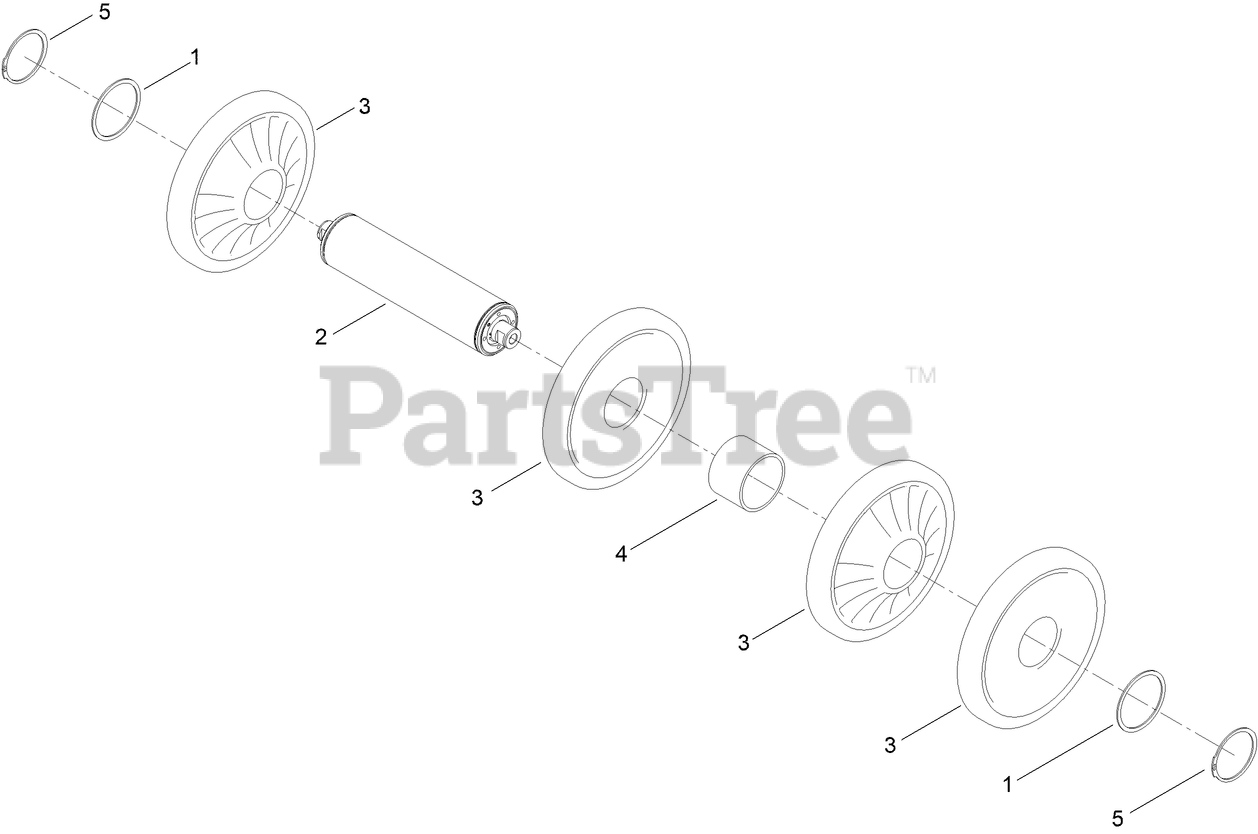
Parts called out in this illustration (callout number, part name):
1	RING-RETAING, TRACK WHEEL
2	AXLE ASS'Y
3	WHEEL 13 1/2'
4	SPACER-WHEEL
5	RING-RETAINING,EXTERNAL 4IN
